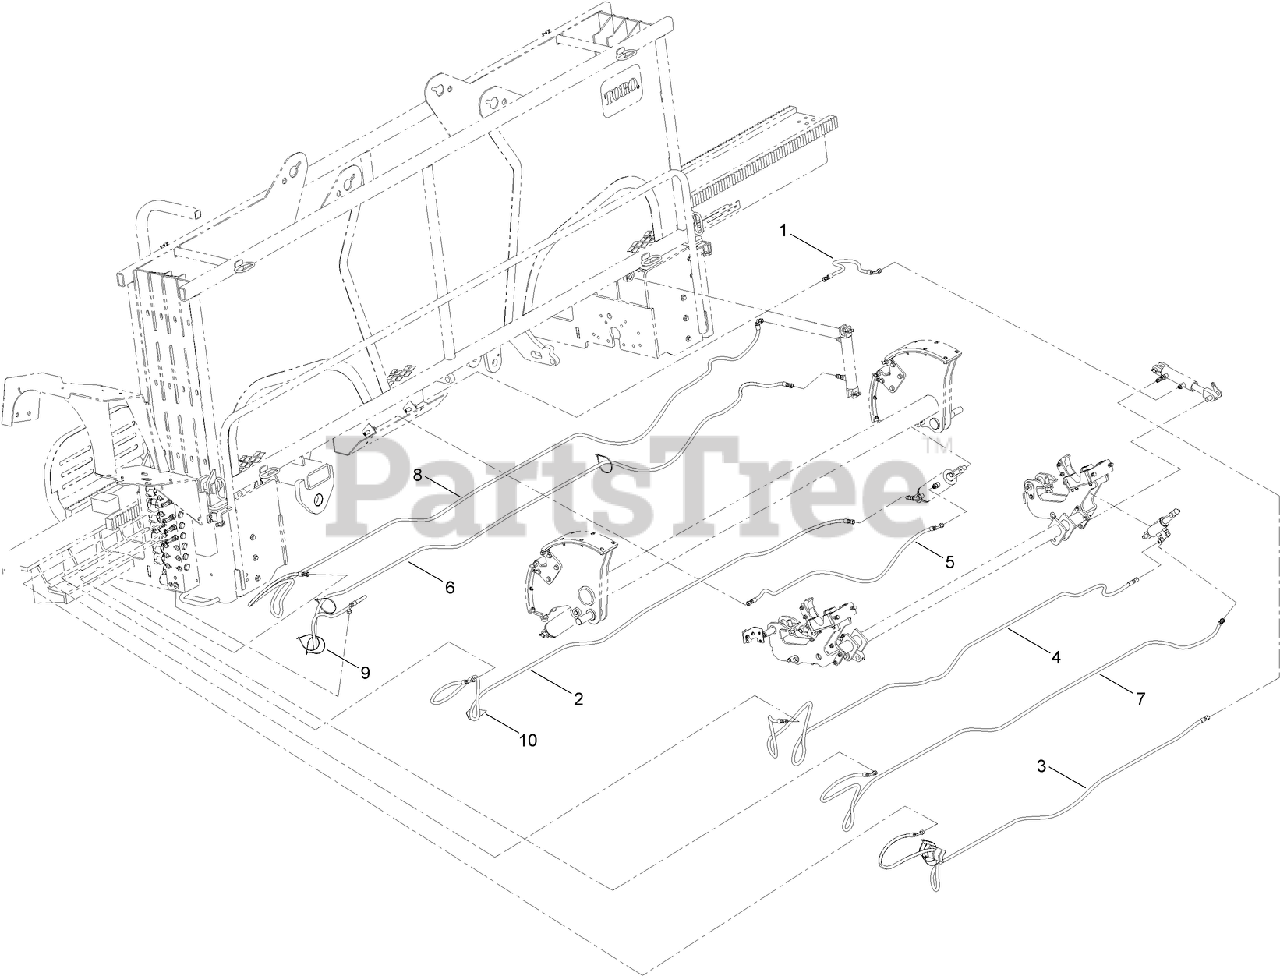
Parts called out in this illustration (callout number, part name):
1	HOSE ASM-HYD
2	HOSE ASM-HYD
3	HOSE ASM-HYD
4	HOSE ASM-HYD
5	HOSE ASM-HYD
6	HOSE ASM-HYD
7	HOSE ASM-HYD
8	HOSE ASM-HYD
9	TIE-CABLE
10	PROTECTOR-HOSE
